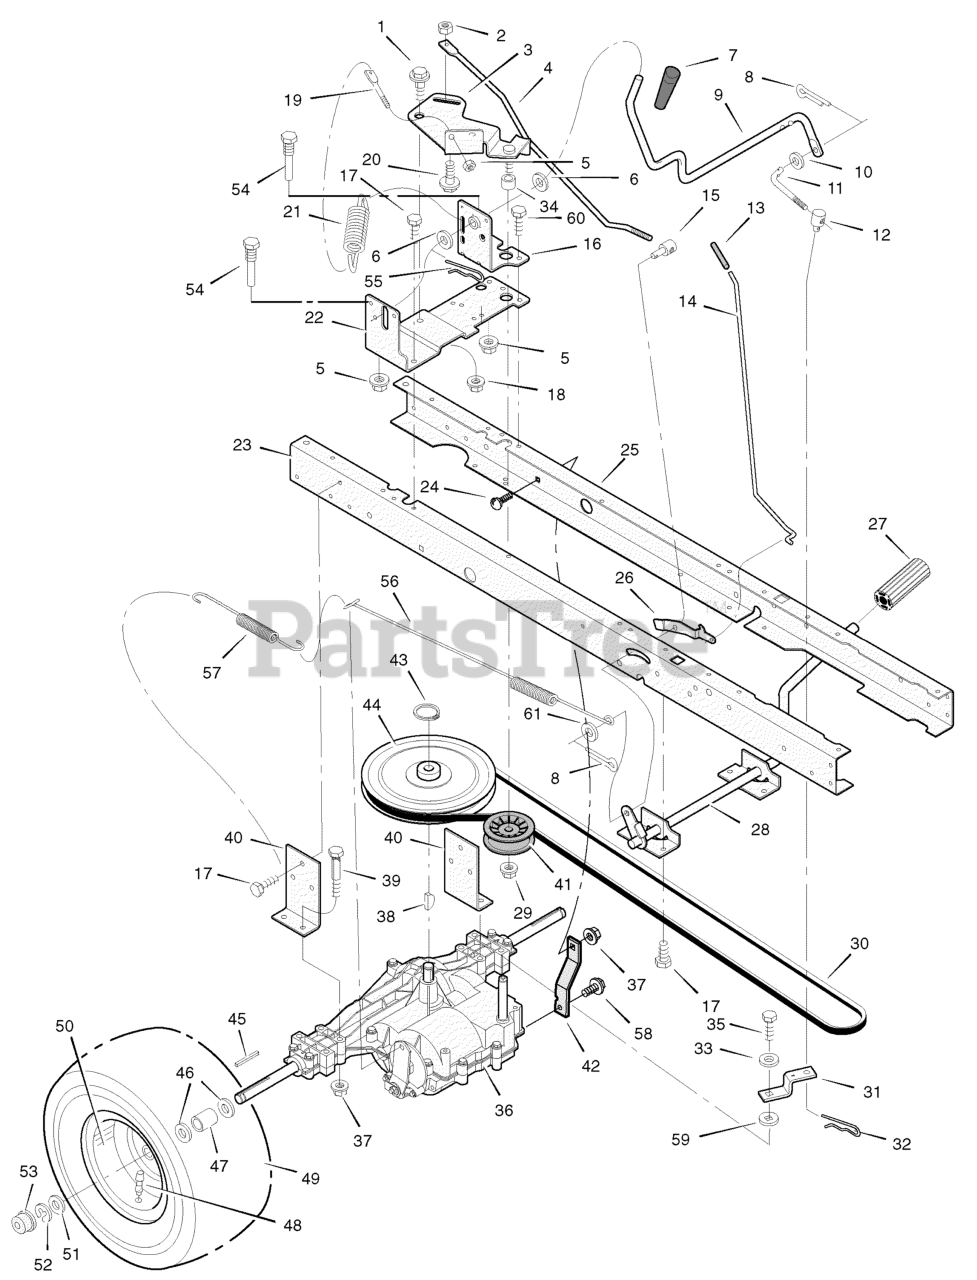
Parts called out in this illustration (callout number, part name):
1	Bolt, Shoulder
2	Nut, Hex
3	ARM, Idler
4	Rod, Clutch
6	Washer
8	Pin, Cotter
9	Lever, Shift
10	Washer
11	Link, Shift
12	Nut, Adjuster
13	Grip
14	Rod, Parking Brake
15	Nut, Adjuster
16	Bracket, Shift Pivot
17	Screw
18	Nut
19	Mount, Stud Spring
20	Bolt, Shoulder
21	Spring, Extension
22	Bracket, Right Shifter
23	Frame, Right
24	Bolt, Carriage
25	Frame, Left
26	Latch, Parking Brake
27	Pedal
28	Lever, Brake/Clutch
29	Nut
30	Belt, Motion Drive
31	Yoke, DANA Shift
32	Pin, Hair
33	Washer
34	Spacer
35	Bolt
36	Transaxle, DANA **
37	Nut
38	Key, Woodruff
39	Bolt
40	Bracket, Transaxle
41	Pulley
42	BRACKET, Torque Strap, LH
43	E-Ring
44	Pulley, Drive
45	Key, Square
46	Washer
47	SPACER, Rear Wheel
48	Stem, Valve
49	Tire *
50	Wheel & Tire Assembly
51	Washer
52	E-Ring
53	Hub Cap
54	Guide, Belt
55	Pin, Hair
56	Spring, Extension
57	Spring, Extension
58	Screw
59	Washer
60	Screw
61	Washer
